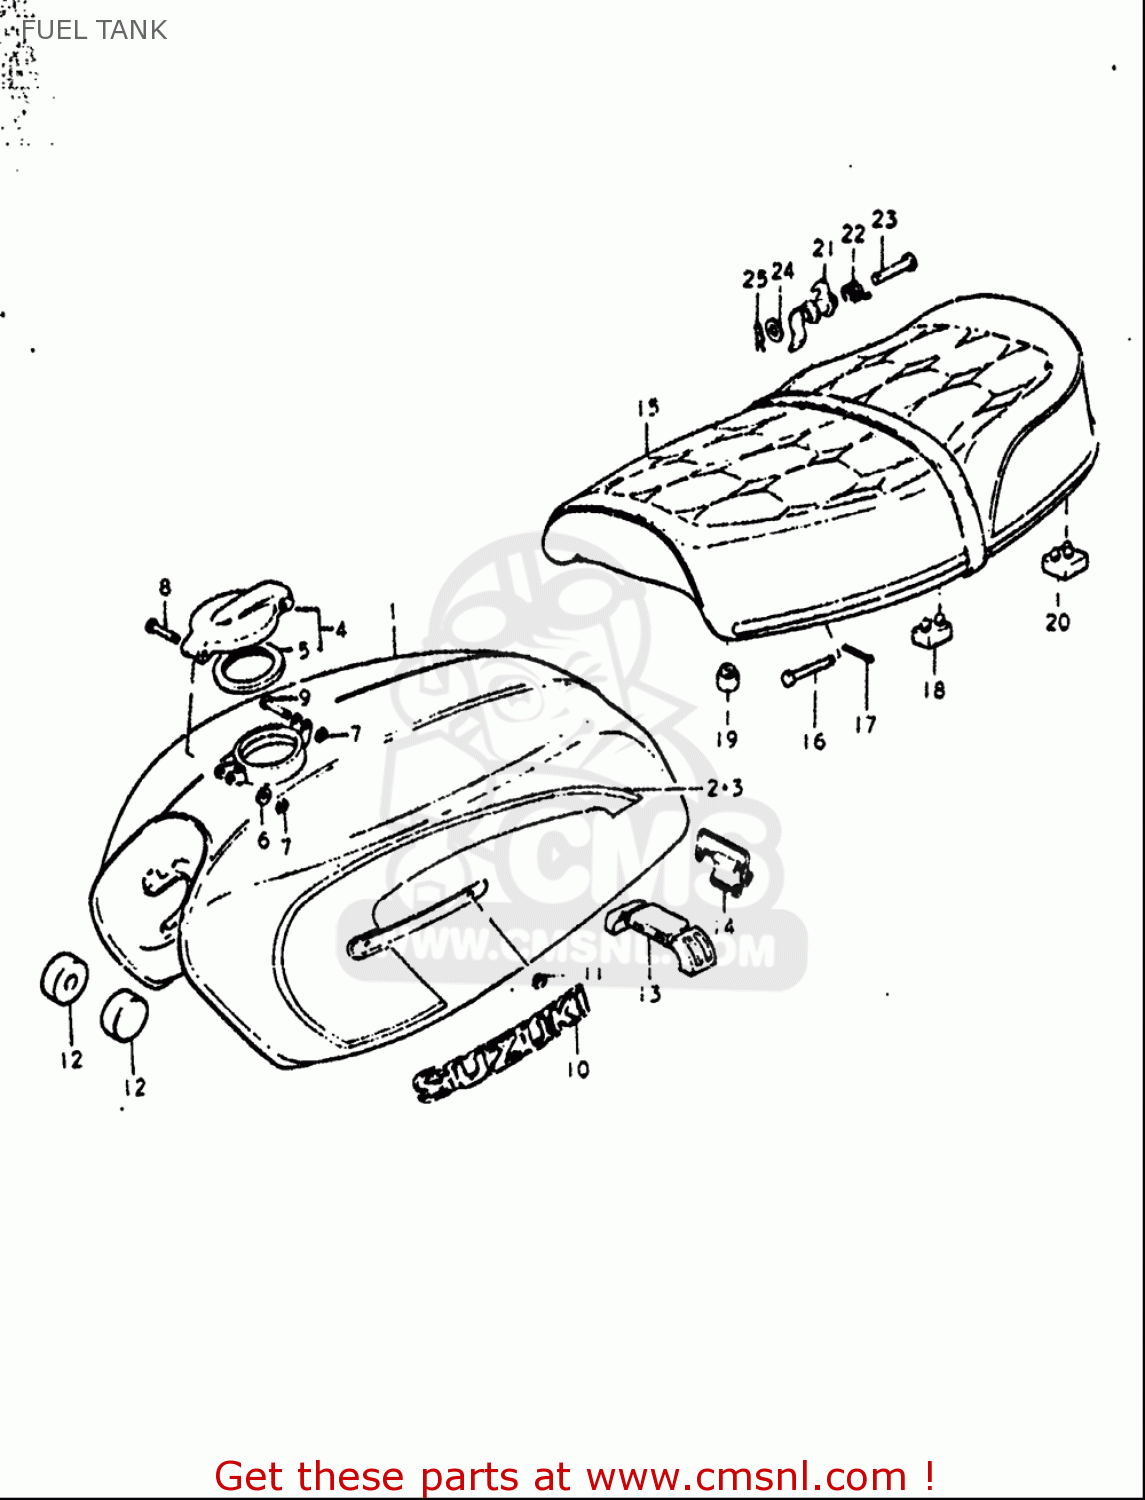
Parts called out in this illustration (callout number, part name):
4	CAP ASSY,FUEL TANK
5	GASKET (NAS)
6	WASHER
7	E RING
11	NUT
12	CUSHION
13	CUSHION
14	BAND
15	SEAT ASSY
16	PIN
17	PIN
18	CUSHION
19	CUSHION(11.5X22X20)
22	SPRING
23	PIN
24	WASHER
